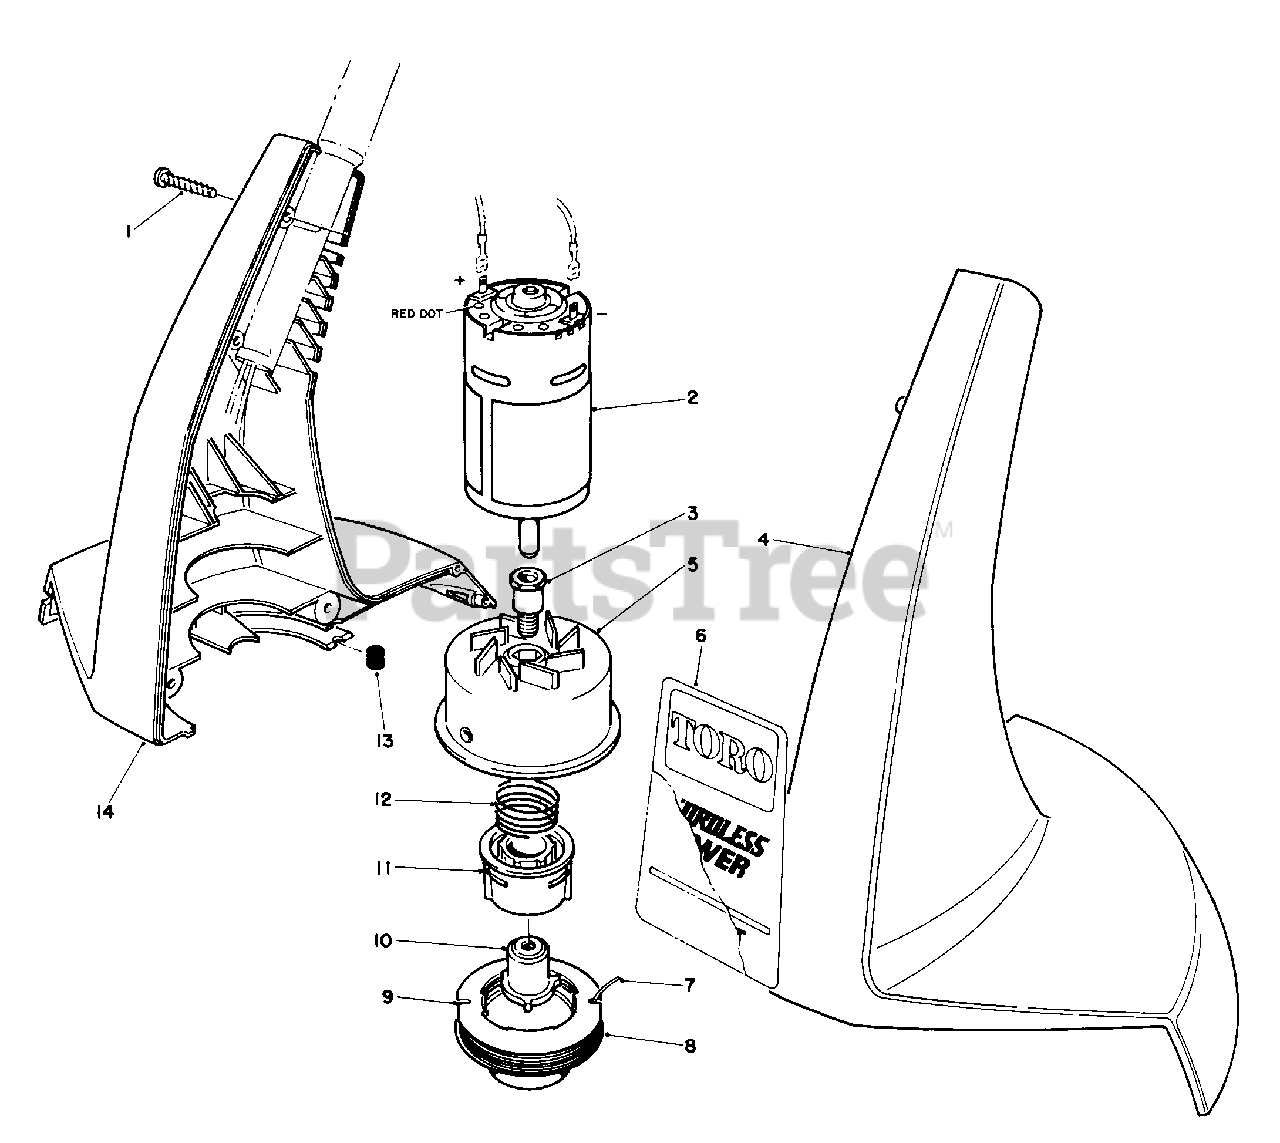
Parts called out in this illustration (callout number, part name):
1	Screw-Thread Forming
2	Motor Assembly (Incl. Ref. #3)
3	Extension-Shaft
4	Housing-L.H.
5	Drum-Assembly
8	Pre-wound Spool (Incl. Ref. #7 & 9)
9	Spool-Cup
11	Core-Spool
12	Spring-Compression
14	Housing-R.H.
